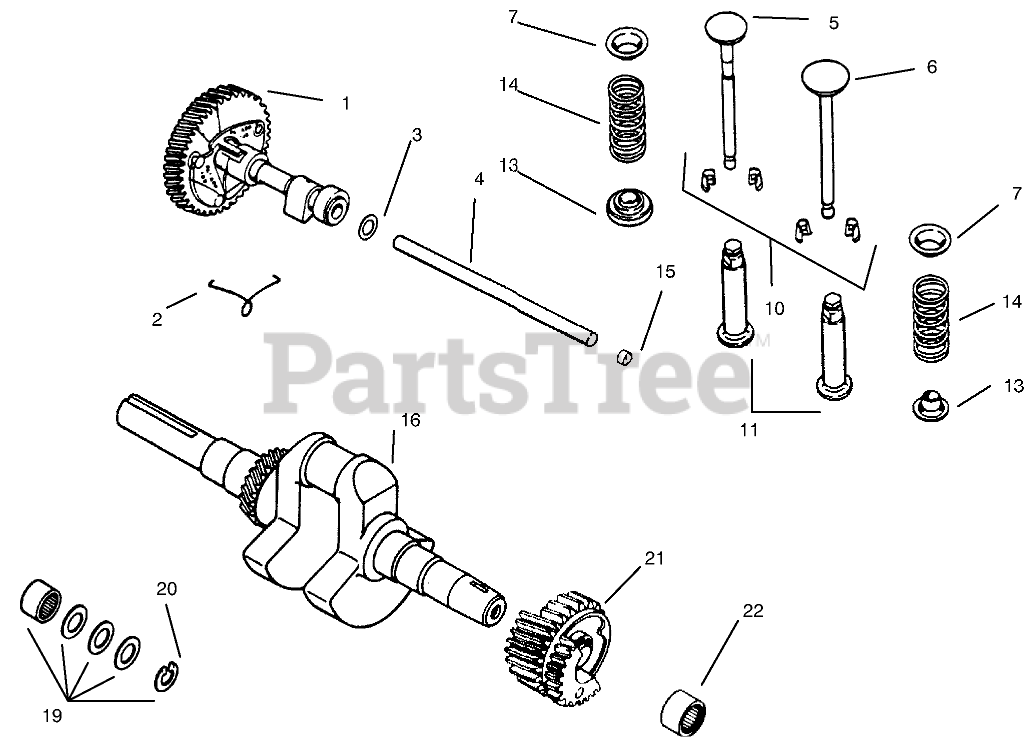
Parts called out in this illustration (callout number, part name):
1	Camshaft ASM INC 2
3	Spacer
4	Pin-Camshaft
5	Valve-Exhaust
6	Valve-Intake
7	Retainer-Spring
8	Spring
10	Kit-Retainer
12	Tappet
13	Retainer-Spring
14	Spring
14	Rotator-Valve
15	Plug
16	Kit-Crankshaft
19	Kit-Spacer
20	Retainer
